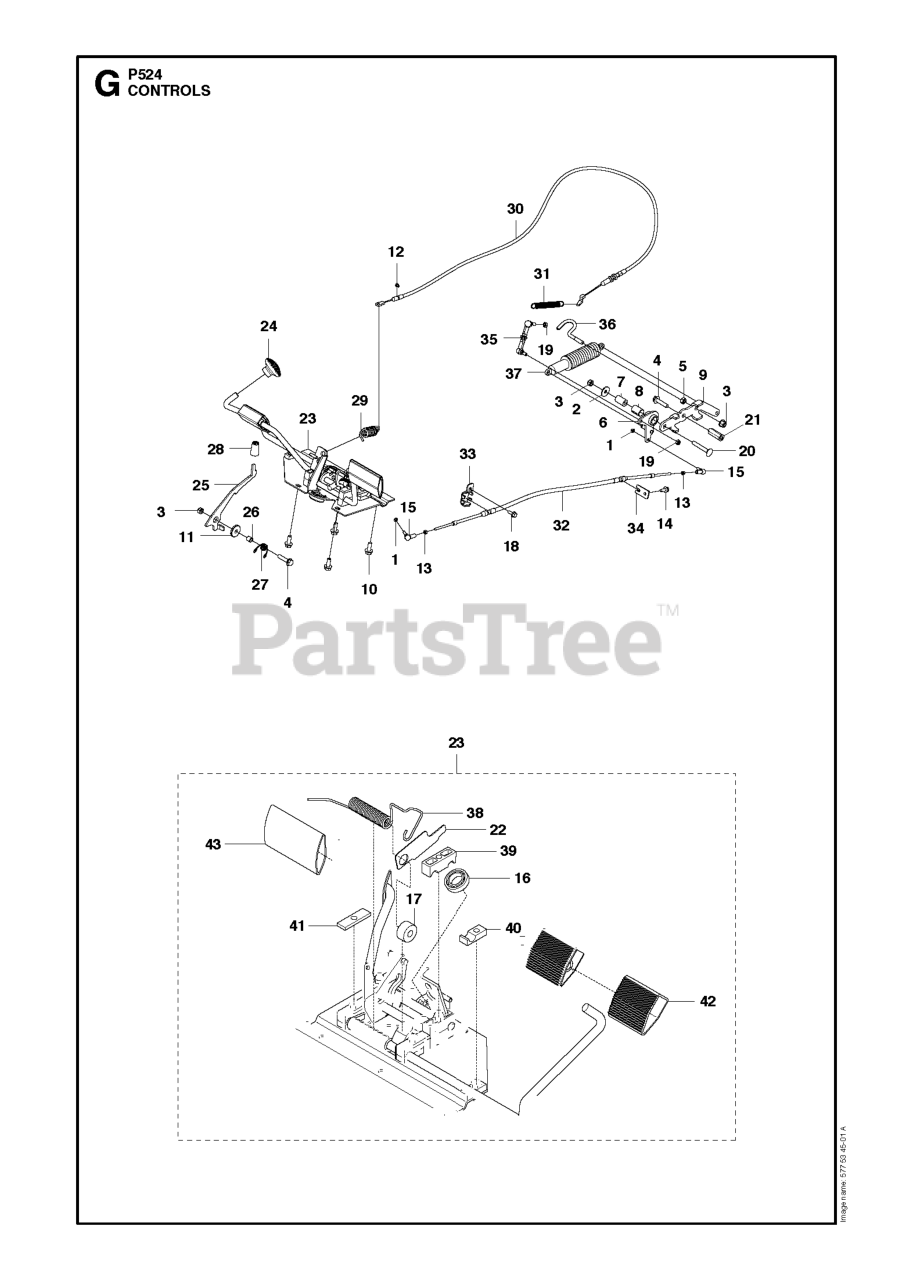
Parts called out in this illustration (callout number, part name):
1	NUT FLANGE - M6
3	NUT FLANGE
4	SCREW EHHFM
5	NUT
11	WASHER
13	LOCKNUT M6
15	CONNECTOR
16	BALL BEARING 6002-2RS1
17	ROLLER
18	SCREW EHHFM
22	PLATE
23	PEDAL ASSEMBLY
24	KNOB
37	SHOCK ABSORBER
38	SPRING
39	PEDAL SHAFT CLAMP
40	SUPPORT
41	PLATE
42	PEDAL RUBBER
43	PEDAL RUBBER, SF
